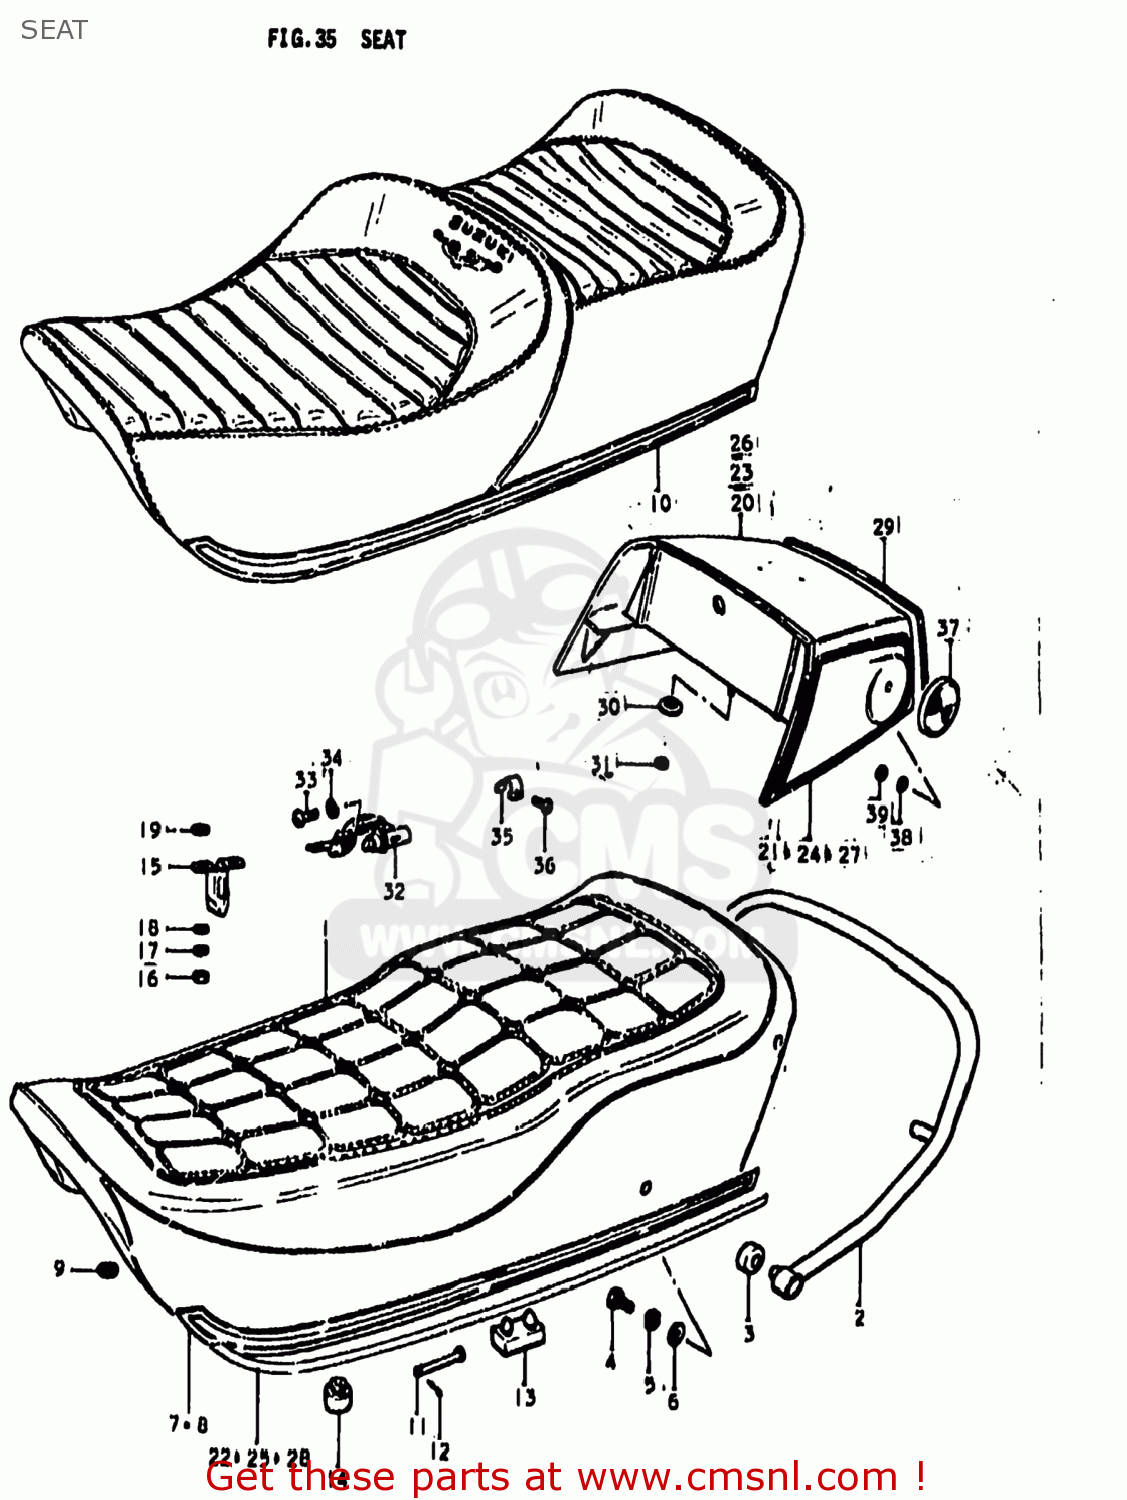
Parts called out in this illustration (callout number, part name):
1	SEAT ASSEMBLY
2	HANDLE,PILLION RIDER
3	CUSHION
4	BOLT
5	LOCK WASHER
6	WASHER
7	MOLE,R
8	MOLE,L
9	NUT
10	SEAT ASSEMBLY
11	PIN
12	PIN
13	CUSHION
14	CUSHION
15	STRIKER,SEAT LOCK
16	NUT
17	LOCK WASHER
18	WASHER
19	WASHER (6.5X20X1.2)
20	COVER,SEAT TAIL
21	TAPE SET
22	TAPE SET
23	COVER,SEAT TAIL
24	TAPE SET
25	TAPE SET
26	COVER,SEAT TAIL
27	TAPE SET
28	TAPE SET
29	MOLDING,SEAT TAIL COVER
30	WASHER
31	NUT 6MM
32	LOCK ASSY,SEAT
33	SCREW
34	LOCK WASHER
35	SPRING,HELMET HOLDER
36	SCREW
37	REFLEX REFLECTOR,RR
38	WASHER
39	NUT
